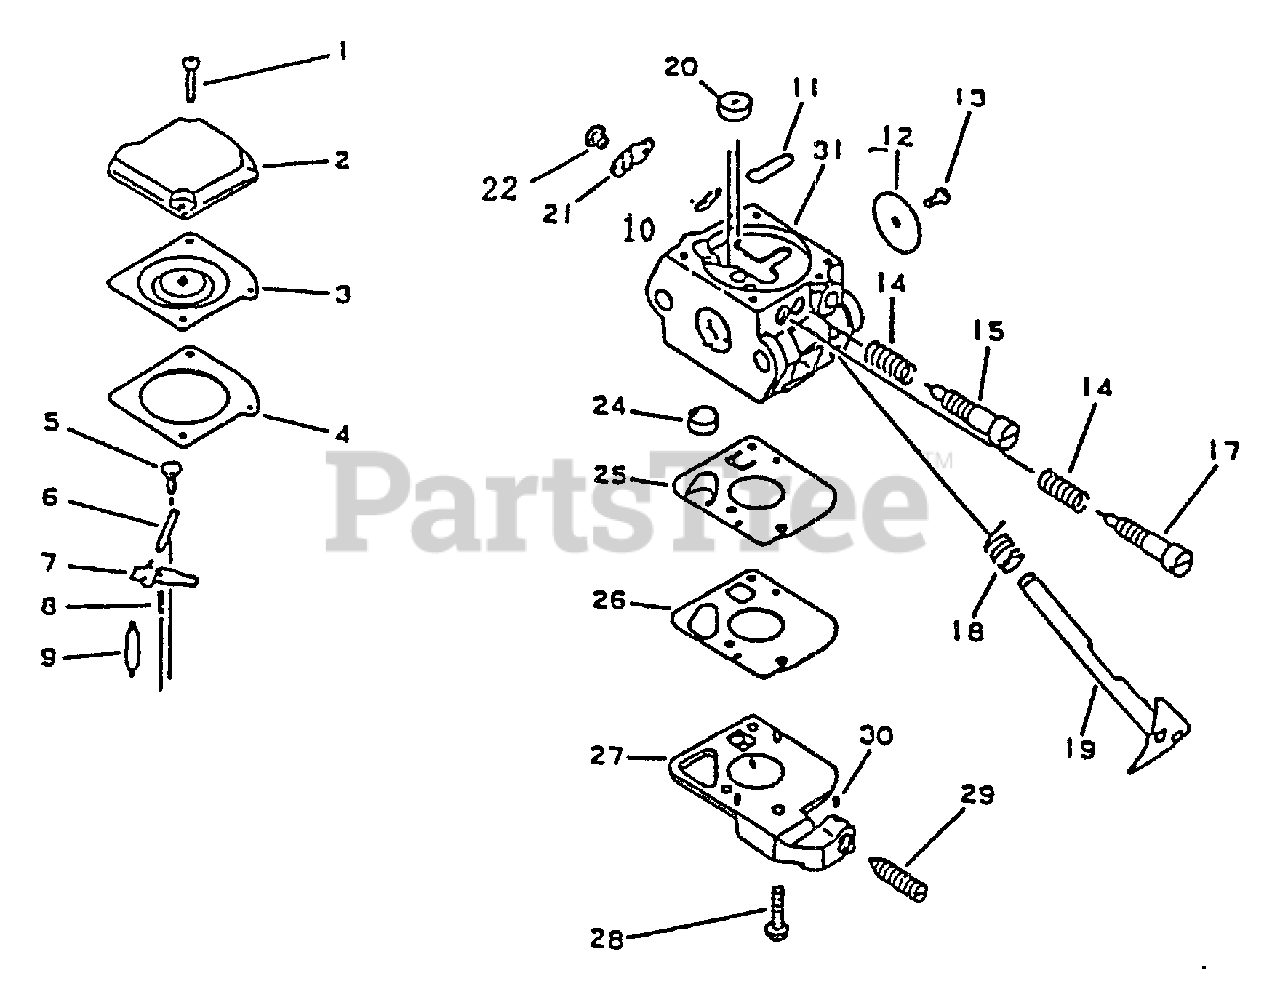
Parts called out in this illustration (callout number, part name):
2	COVER, METERING
3	DIAPHRAGM
4	GASKET, METERING
5	SCREW, METERING LEVER PIN
6	PIN, METERING LEVER
7	LEVER, METERING
8	SPRING
9	VALVE, NEEDLE
10	RING, RETAINING
11	PLUG, WELCH
12	VALVE, THROTTLE
13	SCREW
15	NEEDLE - HIGH SPEED
17	NEEDLE - LOW SPEED
18	SPRING, RETURN
19	SHAFT, THROTTLE
20	NOZZLE, CHECK VALVE
21	LEVER, THROTTLE
22	SCREW
24	STRAINER
25	DIAPHRAGM, PUMP
26	GASKET, PUMP
27	BASE, PURGE
28	SCREW, PUMP COVER
29	SCREW, IDLE ADJUST
30	PIECE, FRICTION
31	BODY, CARBURETOR
